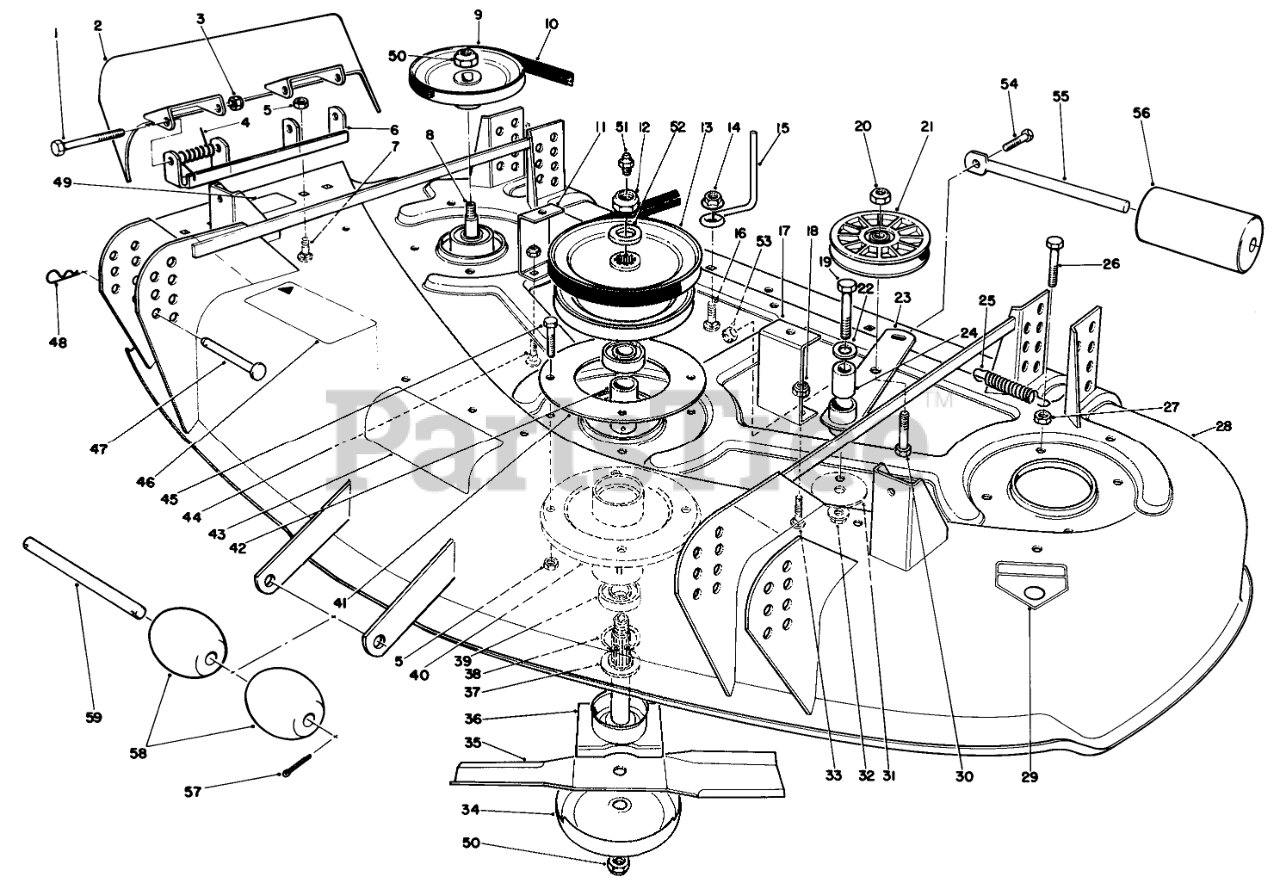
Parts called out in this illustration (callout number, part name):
1	SCREW-HH
2	Deflector-Grass
3	NUT-HEX
4	SPRING
5	NUT-LOCK, CONE
6	PIVOT BRKT WA R/B
7	SCREW-CARR
8	SPDL/BLD RET.WA
9	DECK PULLEY
10	V-BELT
11	Bracket-Cover RH
12	NUT-LOCK, NI
13	PULLEY WA
14	NUT-HF
15	ROD-BELT
16	BOLT-CARR
17	Bracket-Cover
18	NUT-LOCK, NI
19	SCREW-HH
20	NUT-HEX
21	Pulley
22	WASHER-FLAT
23	Idler Arm
24	SLEEVE
25	Spring-Extension
26	SCREW-HH
27	NUT-JAM
28	Housing
29	DECAL-DANGER
30	SCREW-HH
31	WASHER-END
32	NUT-HF
33	SCREW-CARR
34	Cup
35	Blade
36	SPDL/BLD RET.WA
37	IDLER SPACER
38	RING-RETAINING
39	BEARING-BALL
40	Spindle
41	DECK RING
42	BEARING SPACER
43	DECAL
44	BOLT-CARR
45	SCREW-HH
46	CAUTION DECAL
47	PIN-CLEVIS
48	PIN-HAIR
49	DECAL-CAUTION, BLADE
50	NUT-LOCK NI
51	FITTING-GREASE
52	WASHER
53	NUT-LOCK, NI
54	SCREW-HH
55	ROD-ROLLER
56	ROLLER-DECK
57	Pin-Cotter
58	ROLLER
59	SHAFT-ROLLER
